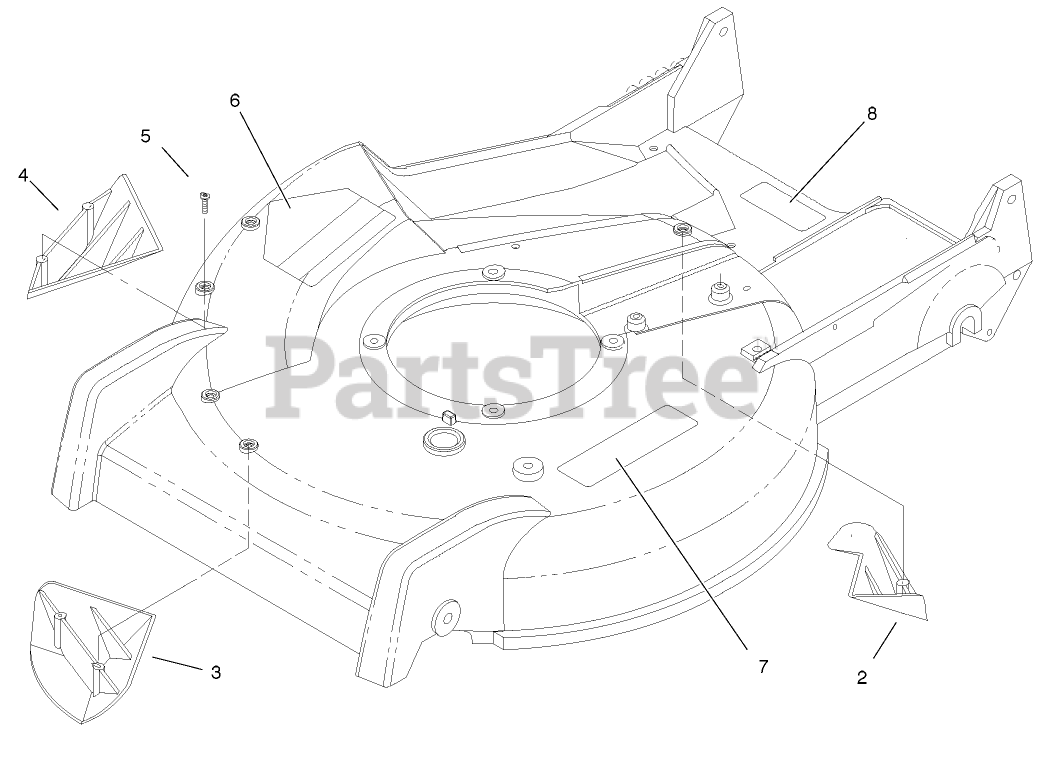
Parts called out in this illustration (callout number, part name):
2	KICKER-REAR
3	KICKER-FRONT
4	KICKER-RH
5	SCREW-PPH
6	DECAL-DANGER
8	DECAL-WARNING
